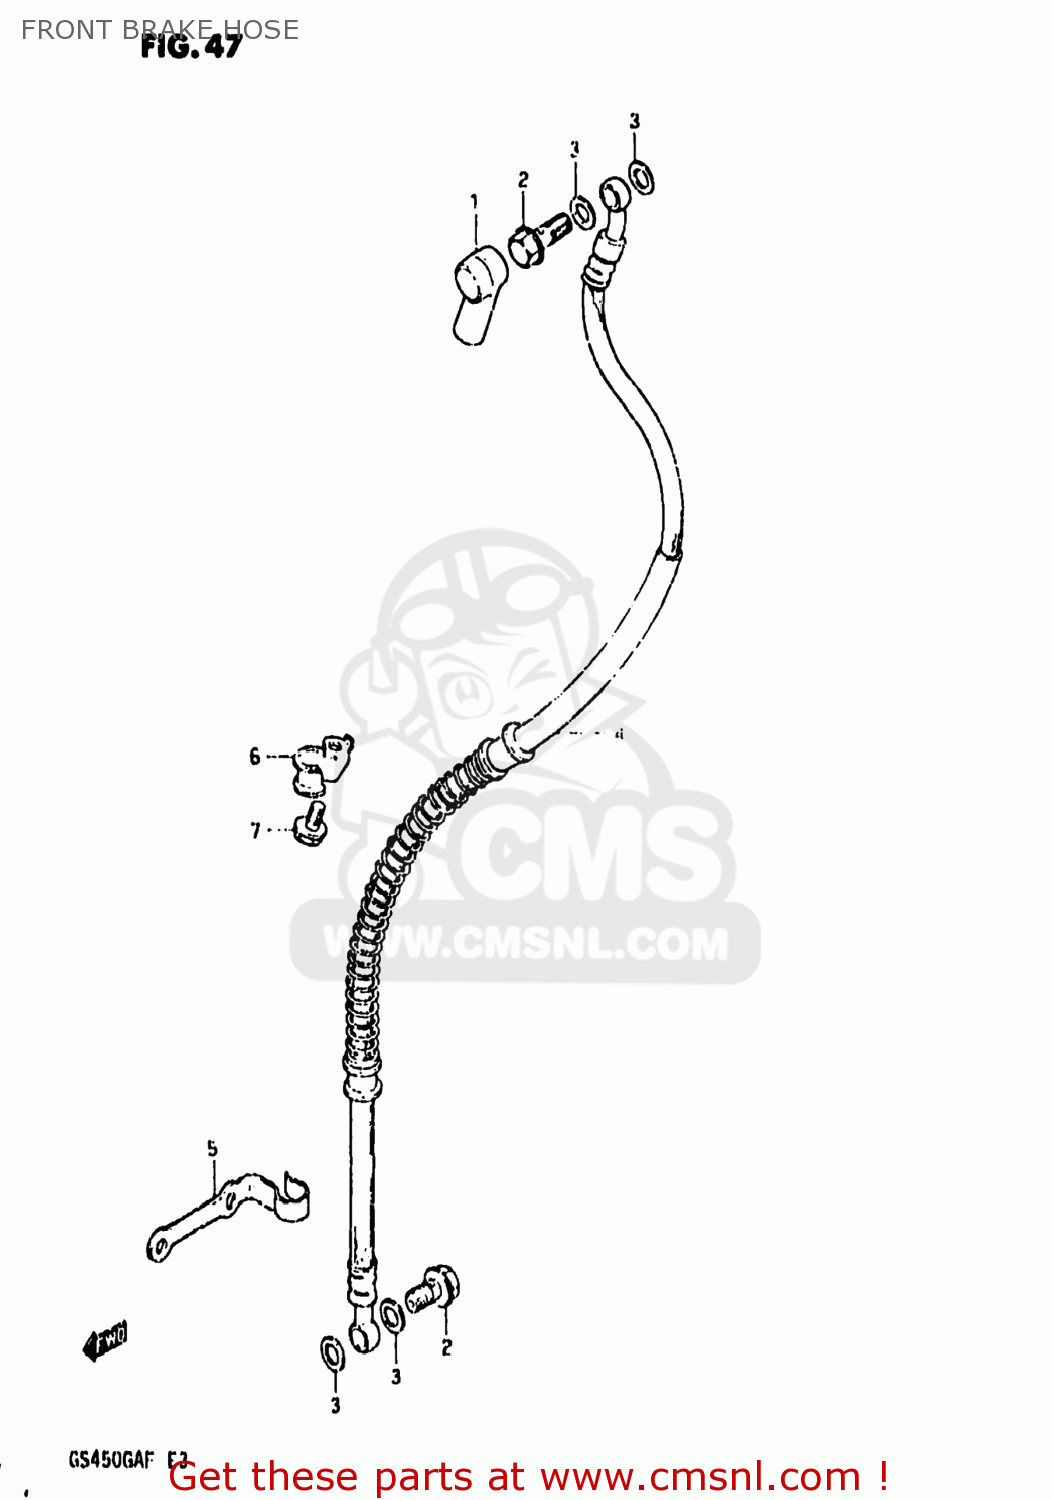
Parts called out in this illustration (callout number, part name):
1	BOOT,MASTER CYLINDER
2	BOLT UNION
3	WASHER(10X15X1.5)
4	HOSE,BRAKE
5	GUIDE,BRAKE HOSE NO.2
6	GUIDE,BRAKE HOSE NO.3
7	BOLT
